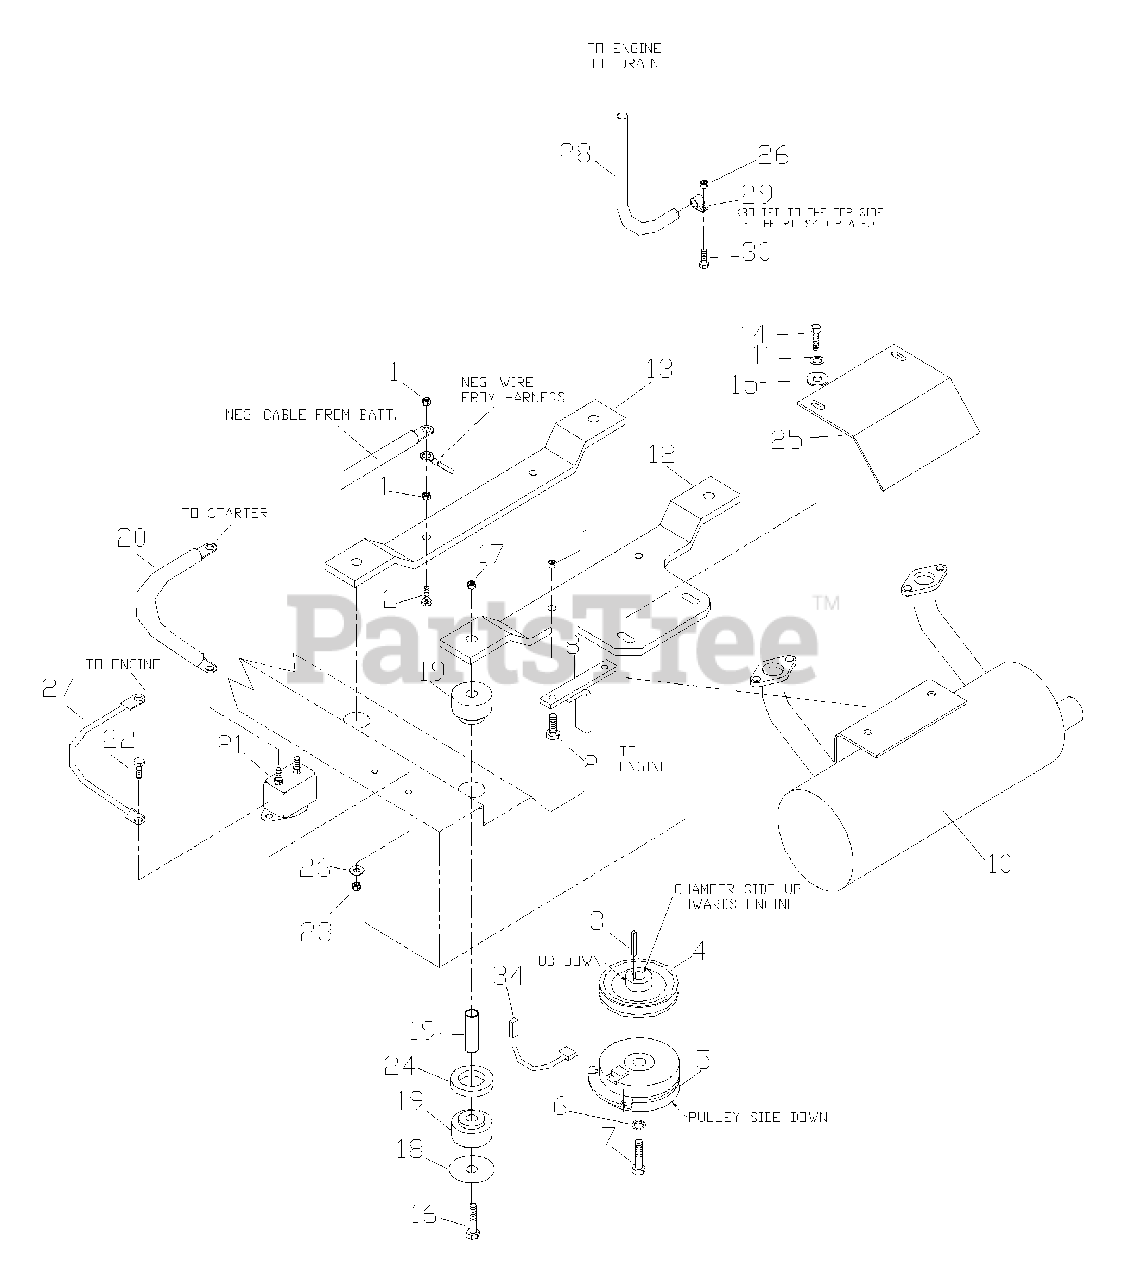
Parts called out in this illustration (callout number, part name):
1	NUT 5/16 LOCK
2	HCS 5/16 X 1.75
3	KEY 1/4 SQ
6	WASHER 7/16 LOCK
7	HCS 7/16F X 2.5
8	CLUTCH TIE DOWN
9	KAWASAKI PIGTAIL
11	WASHER 5/16 LOCK
12	ENGINE MOUNT
13	ENGINE MOUNT
14	HCS 5/16 X 750
15	WASHER 5/16 FLAT
16	HCS 1/2 X 3.25
17	NUT 1/2 NYLOC
20	CABLE, POSITIVE
22	HCS 1/4 X 625
23	NUT 1/4 CTR LOCK
25	MUFFLER GUARD
26	WASHER 1/4 INT TOOTH
27	GROUND WIRE
28	OIL DRAIN HOSE
30	HCS 1/4 X 750
34	CLUTCH PIGTAIL
